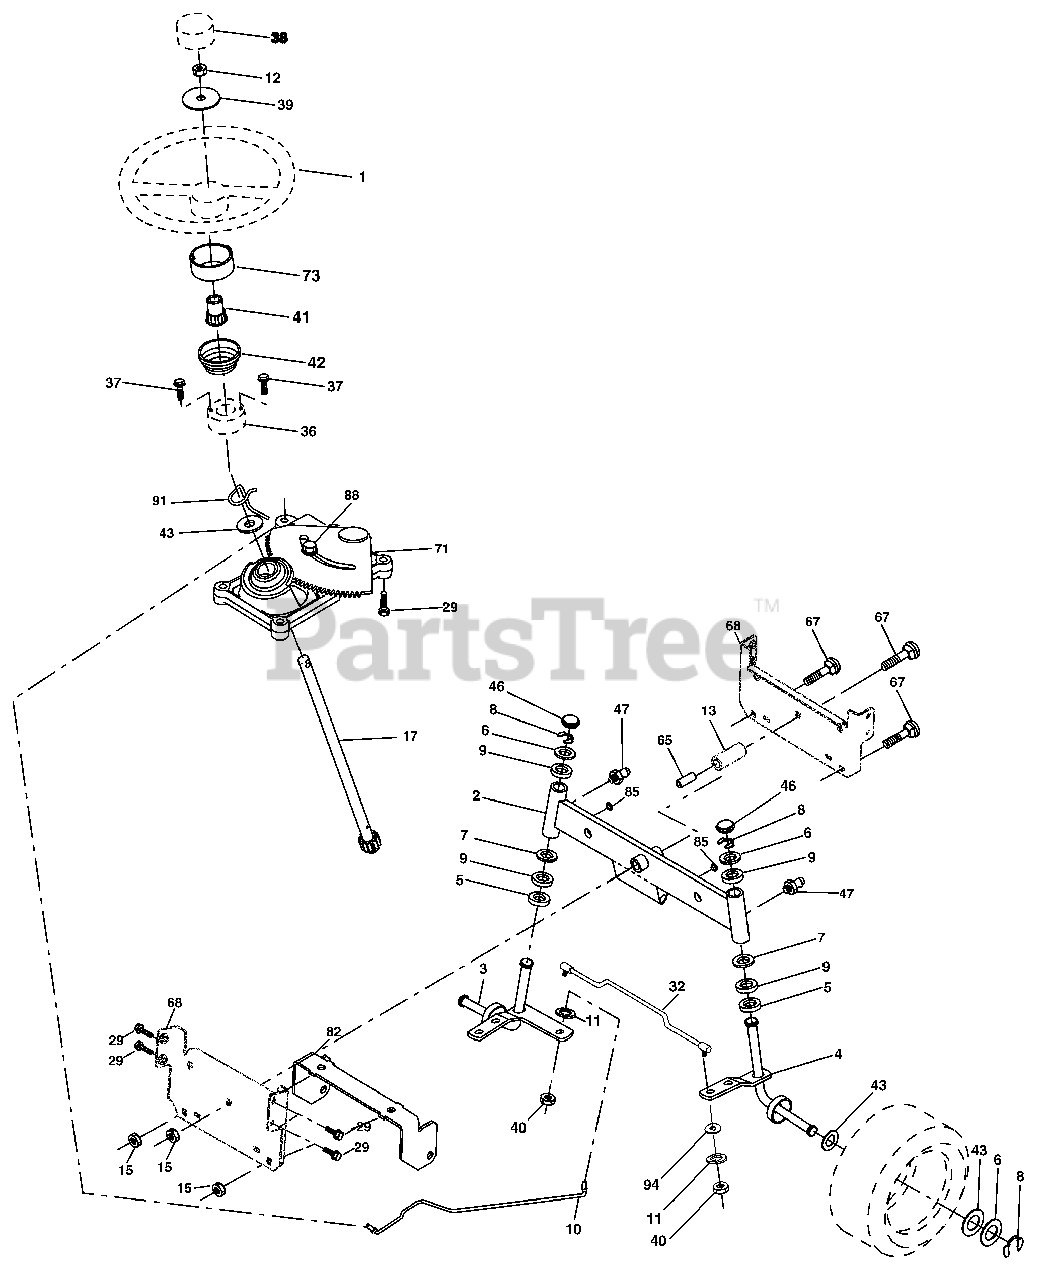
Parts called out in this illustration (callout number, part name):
1	Wheel Steering
2	Axle Asm.
3	Spindle Asm LH
4	Spindle Asm RH
5	Bearing Race Thrust Harden
6	Washer 25/32 X 1-5/8 X 16 Ga
7	Washer 27/32 x 1-1/4 x 16 Ga.
8	Ring Klip #t5304-75
9	Bearing
10	Link Drag
11	Washer Lock Hvy Hlcl Spr 3/8
12	Nut Hex Jam Toplock 1/2-20 UNF
13	Spacer Brg Axle Front
15	Nut Hex Flange Lock
17	Shaft Asm Strg
29	Screw 3/8-16 x 3/4
32	Rod Tie
36	Bushing Strg
37	Screw TT #32.5 x 5 x 3/8 Flange
38	Cap Wheel Steer
39	Washer 9/16 x 1-1/2 x 11 Ga.
40	Nut Lock Center 3/8-24 Unf
41	Adaptor Wheel Strg
42	Boot Steering
43	Washer 25/32 x 1 1/4 x 16 Ga
46	Cap Spindle Fr Top Blk
47	Fitting Grease
65	Spacer Brace Axle
67	Bolt Rdhd Sqn 3/8-16 x 2-1/4
68	Brace, Axle
71	Steering Asm.
73	Extension Steering
82	Bracket Susp Chassis Front
85	Fastener Christmas Tree
88	Bolt Shoulder 7/16-20 Unc
91	Clip
94	Washer 3/8 x 7/8 x 14 Ga.
